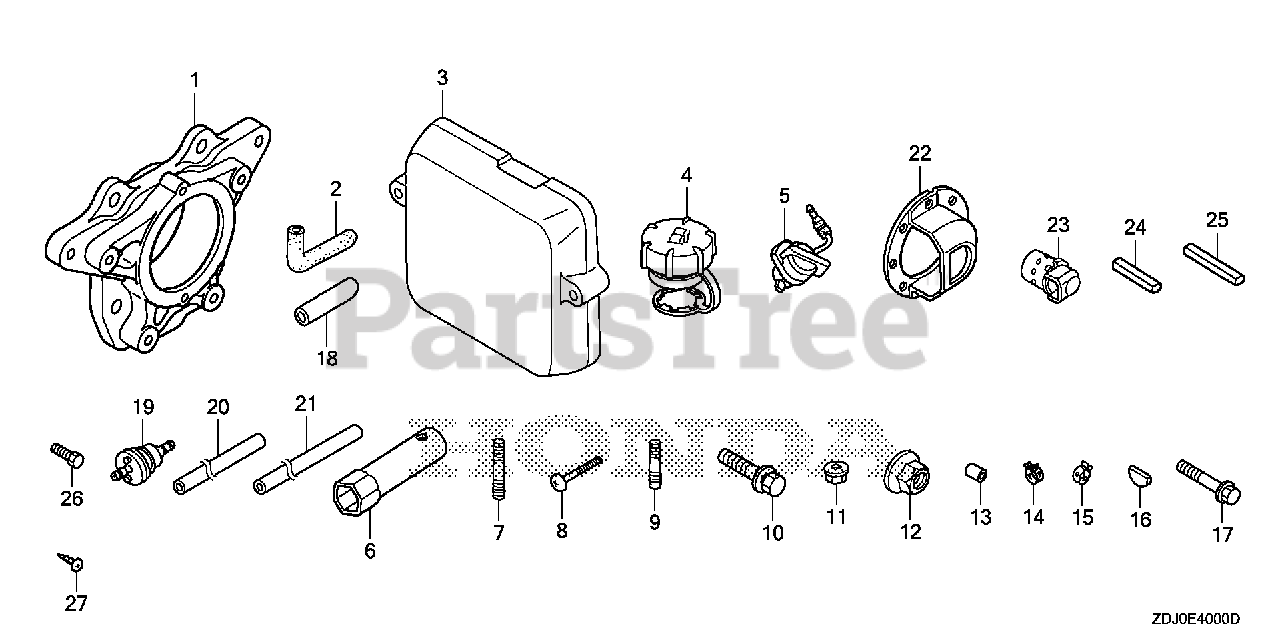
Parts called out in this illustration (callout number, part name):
1	FLANGE, P.T.O.
4	CAP ASSY., FUEL TANK
5	SWITCH ASSY., ENGINE STOP
6	WRENCH, SPARK PLUG
7	BOLT, STUD (10X32)
11	NUT, FLANGE (10MM)
13	PIN, DOWEL (6X10)
14	CLIP, TUBE (D8)
15	CLIP, TUBE (D8.5)
